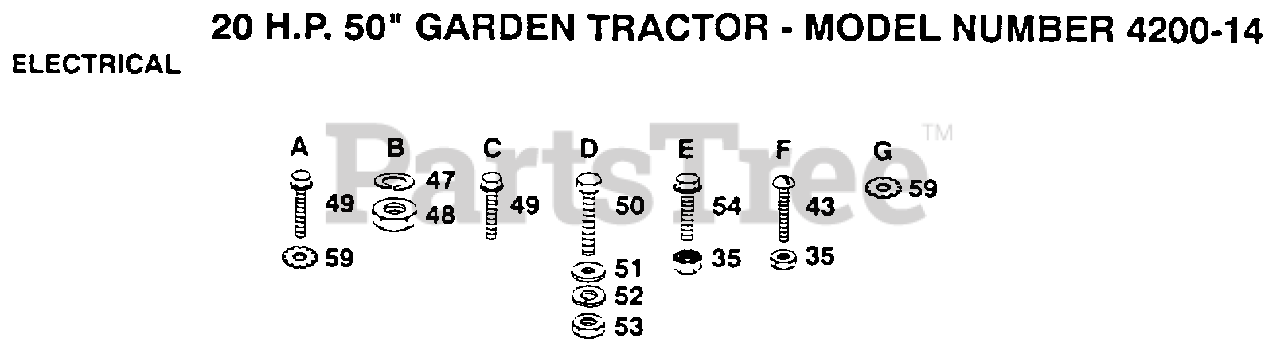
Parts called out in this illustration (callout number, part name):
35	"NUT,KEPS"
48	NUT
49	SCREW ST
50	BOLT LT
51	WASHER
52	LOCKWASHER
54	SCREW
59	LOCKWASHER
